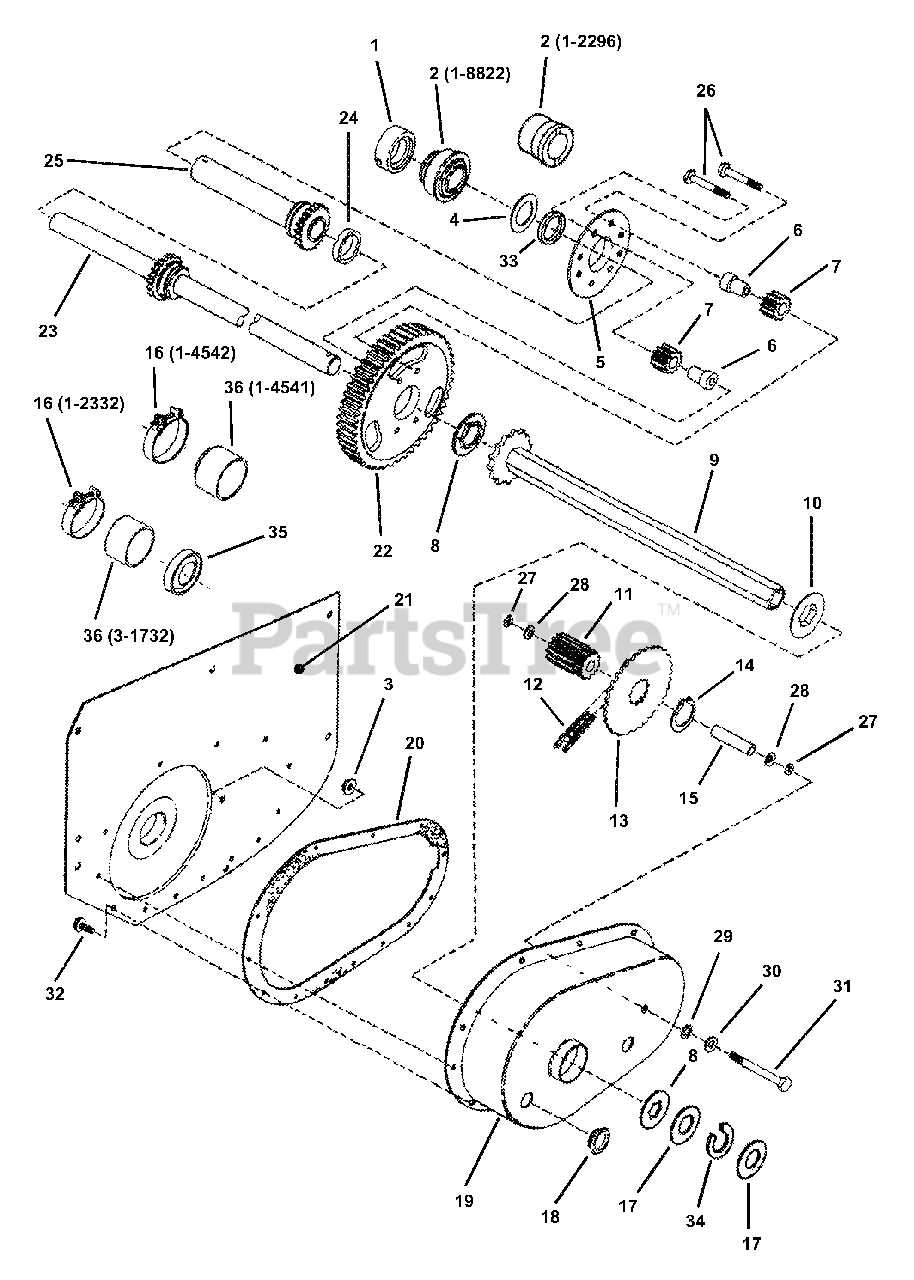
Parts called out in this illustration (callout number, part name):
1	COLLAR, Lock
2	BALL BEARING, Axle (in 60662)
3	NUT, 5/16-24 Hex Flange Lock
4	WASHER, Thrust
5	PLATE, Differential
6	SPACER, Pinion
7	GEAR, Differential Pinion
8	WASHER, Thrust
9	ASSEMBLY, Drive Hex Tube
10	WASHER, Hex Nylon Splash
11	GEAR, 11 Teeth- 10 Pitch
12	CHAIN, 46 Pitch (No. 35)
13	SPROCKET
14	RING, External Retaining
15	SPACER
16	CLAMP, Boot 2"
17	THRUST WASHER
18	PLUG, Oil Fill & Check
19	CASE, Transmission
20	GASKET, Transmission Case
21	FENDER, Right Hand
22	GEAR, 63 Teeth- 10 Pitch
23	AXLE, Long
24	SPACER
25	AXLE, Short
26	SCREW, 5/16-24 x 1-5/8" Hex Cap Special Lock
27	O-RING, 5/16"
28	WASHER, 5/16" Belleville
29	WASHER, 5/16" External Tooth Lock
30	WASHER, 5/16" Flat
31	BOLT, 5/16-24 x 2-5/8" Idler
32	SCREW, 1/4-20 x 5/8" Hex Washer Self-Tap
33	SPACER, Short Axle
34	SHIM WASHER (Split)
35	SEAL
36	BOOT, Large
